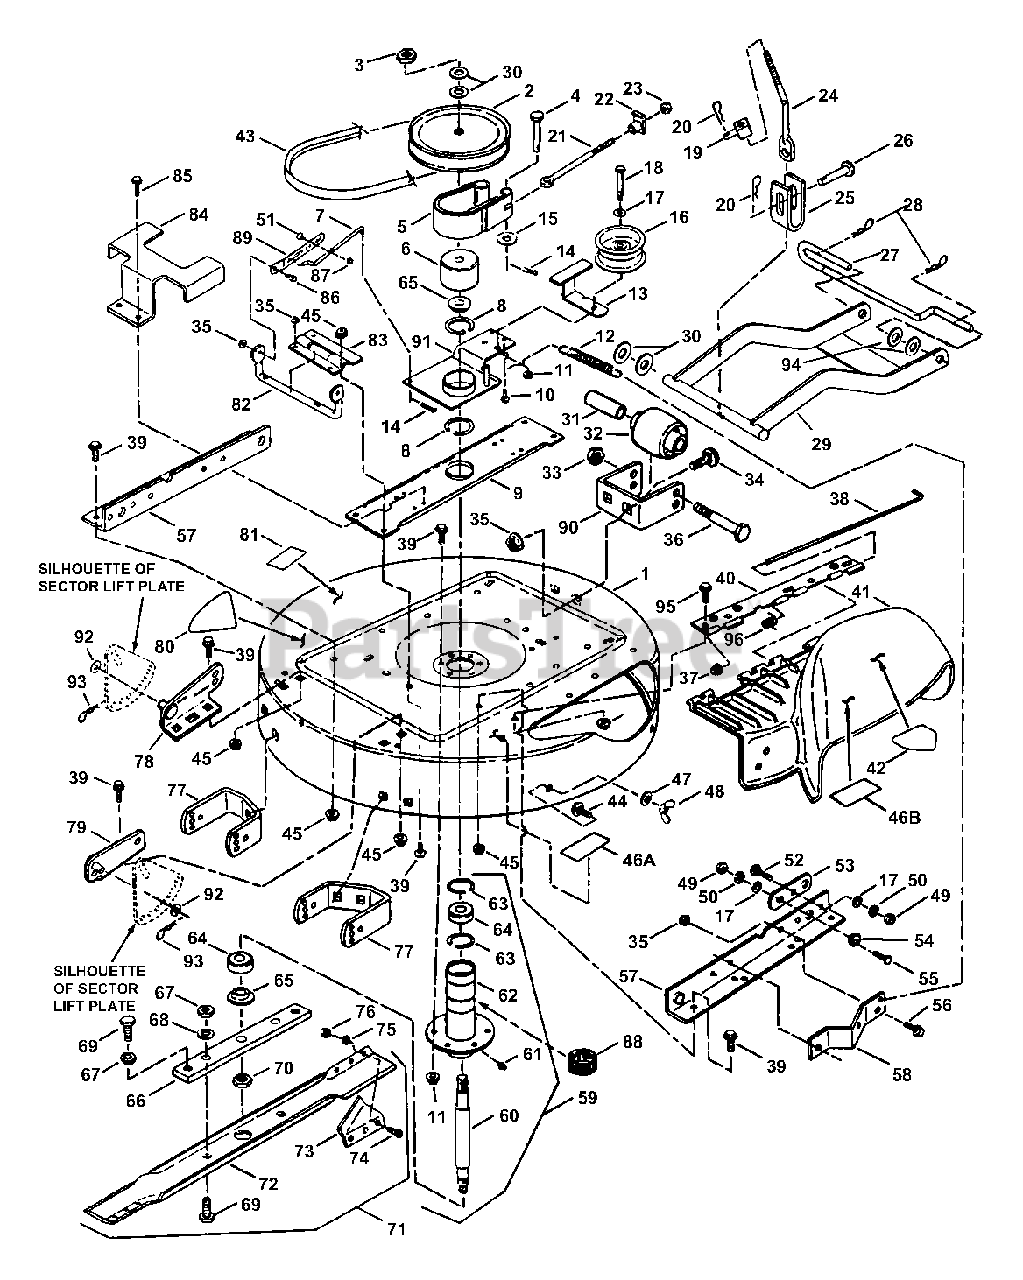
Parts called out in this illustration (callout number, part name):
1	ASSEMBLY, Deck 33" Cutting
2	PULLEY, Spindle, 7" O.D.
3	NUT, 3/4-16 Hex Jam
4	PIN, 1/4 x 1-1/4" Clevis
5	ASSEMBLY, Brake Band
6	DRUM, Brake
7	ROD, Link, Clutch/Brake
8	RING, 2" External Retaining
9	BRACE, Spindle
10	SCREW, 5/16-18 x 3/4" Self-Tapping
11	NUT, 3/8-16 Hex Center Lock, Gr. 5
12	SPRING, Clutch & Brake
13	GUIDE, Belt
14	COTTER-PIN, 3/32 x 3/4"
15	WASHER, 1/4" I.D. x 5/8" O.D. Flat
16	PULLEY, Idler, 4" O.D.
17	WASHER, 3/8" Flat
18	SCREW, 3/8-16 x 1-3/4" Cap
19	SWIVEL, Brake
20	PIN, 1/4 x 1-1/8" Hair
21	BOLT, 1/4-20 Eye
22	NUT, 1/4-20 Tee
23	NUT, 1/4-20 Hex, Grade 5
24	ROD, Front Lift
25	BRACKET, Front Lift Hanger
26	PIN, 3/8 x 1-1/2" Clevis
27	PIN, Front Deck Hanger
28	HAIRPIN, 5/8"
29	LIFT, Front Arm
30	WASHER, 3/4" I.D. Flat
31	SPACER
32	WHEEL, Gage
33	NUT, 3/8-24 Hex Center. Lock, Gr. 5
34	BOLT, 5/16-18 x 1/2" Carriage Gr. 5
35	NUT, 5/16-18 Hex Lock, Gr. 5
36	SCREW, 3/8-24 x 3-3/4" Cap, Gr. 5
37	PALNUT, 1/4 Hex
38	PIN, Hinge
39	BOLT, 3/8-16 x 3/4" Flange Lock, Gr. 5
40	HINGE, Deflector
41	ASSEMBLY, Deflector
41	DEFLECTOR, Discharge
42	DECAL, Danger (Cut Finger)
43	BELT, Drive, 33" Cutting Deck
44	BOLT, 5/16-18 x 3/4" Carriage Gr. 5
45	NUT, 3/8-16 Hex Flange Lock
46A	DECAL - CAUTION, Deflector
46B	DECAL - CAUTION, Deflector
47	WASHER, 5/16 Flat
48	NUT, 5/16-18 Wing
49	NUT, 3/8-16 Hex, Grade 5
50	WASHER, 3/8 Split Lock
51	BOLT, 1/4-20 x 1/2" Flange Lock. Gr. 5
52	BOLT, 3/8-16 x 3/4" Carriage, Gr. 5
53	LINK, Adjustment
54	ECCENTRIC, Leveling
55	SCREW, 3/8-16 X 1" Hex Cap, Gr. 5
56	BOLT, 5/16-18 x 1/2" Flange Lock, Gr. 5
57	RAIL, Side
58	ANCHOR, Brake
59	ASS'Y, Spindle
60	SPINDLE
61	FITTING, Lube (Press fit for .187 hole-no ball)
62	HOUSING, Spindle
63	RING, Retaining
64	BEARING, Spindle
65	WASHER, Spindle
66	HOLDER, Blade
67	NUT, 1/2-20 Hex Jam
68	WASHER, 1/2 Int. Tooth Lock
69	SCREW, 1/2-20 x 1-1/4" Cap Gr. 5
70	NUT, 5/8-18 Hex Lock, Gr. B or 5
71	ASSEMBLY, Blade & Air Lift
72	BLADE, 33" Cutting Deck Euro
73	AIR-LIFT
74	SCREW, 5/16-24 x 11/16" Machine
75	WASHER, 5/16 Int. Tooth Lock
76	NUT, 5/16-24 Hex, Grade 5
77	BRACKET, Gage Wheel (Rear)
78	BRACKET, Rear Deck Lift, Left Side
79	BRACKET, Rear Deck Lift, Right Side
80	DECAL, 33" Hi-Vac
81	DECAL - CAUTION (Rotating Blades)
82	ARM, Pivot
83	BRACKET, Pivot Arm
84	GUIDE, Belt
85	SCREW, 5/16-18 x 5/8" Self-Tap.
86	SCREW, 5/16-18 x 3/4" Shoulder
87	NUT, 1/4-20 Hex Flange Lock, Gr. 5
88	RING, Tolerance
89	BRACKET, Link, Clutch/Brake
90	BRACKET, Gage Wheel (Front)
91	ARM, Idler
92	WASHER, 3/8" Flat
93	HAIRPIN, 3/8"
94	WASHER, 1/2" I.D. Flat
95	BOLT, 3/8-16 x 3/4" Flange Lock, Gr. 5
96	SPRING, Hinge
